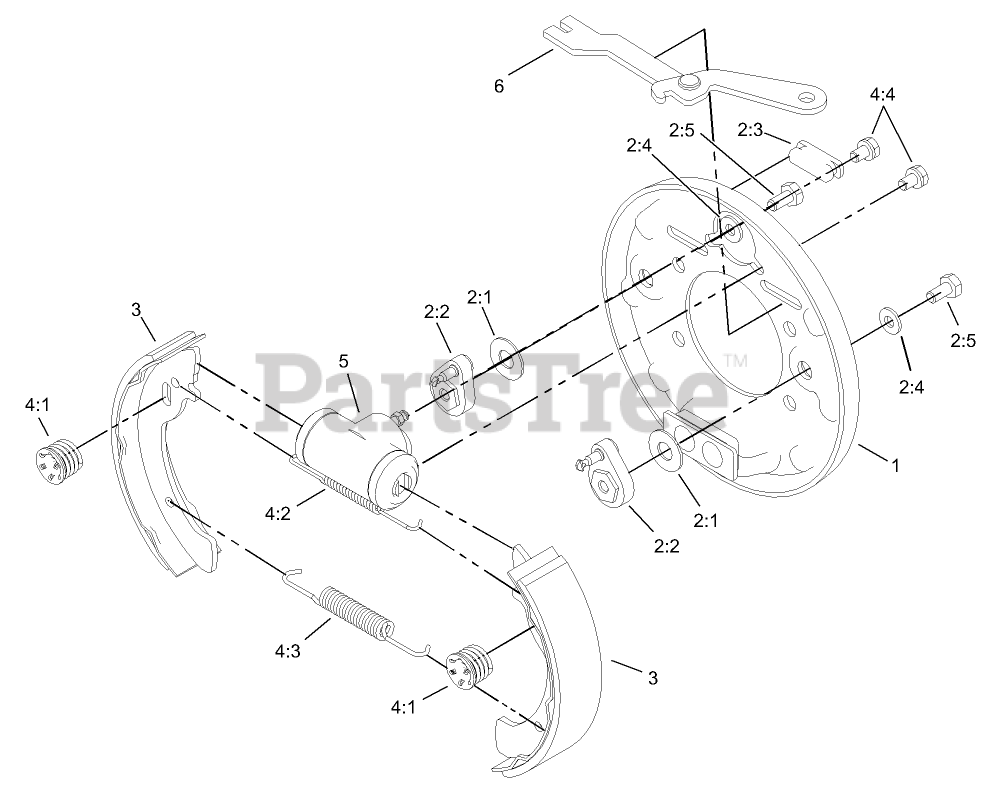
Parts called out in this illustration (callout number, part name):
1	BACKING PLATE ASM
2	ADJUSTER KIT
2:1	WASHER-BELLVILLE
2:2	ADJUSTER LEVER ASM
2:3	COVER-DUST
2:4	Washer
2:5	Bolt
3	SHOE AND LINING KIT
4	HARDWARE KIT
4:1	SHOE HOLD DOWN SPRING ASM
4:2	SPRING-UPPER
4:3	SPRING-LOWER
4:4	Loose Parts Package
5	WHEEL CYLINDER ASM
6	LH PARK BRAKE LEVER ASM
